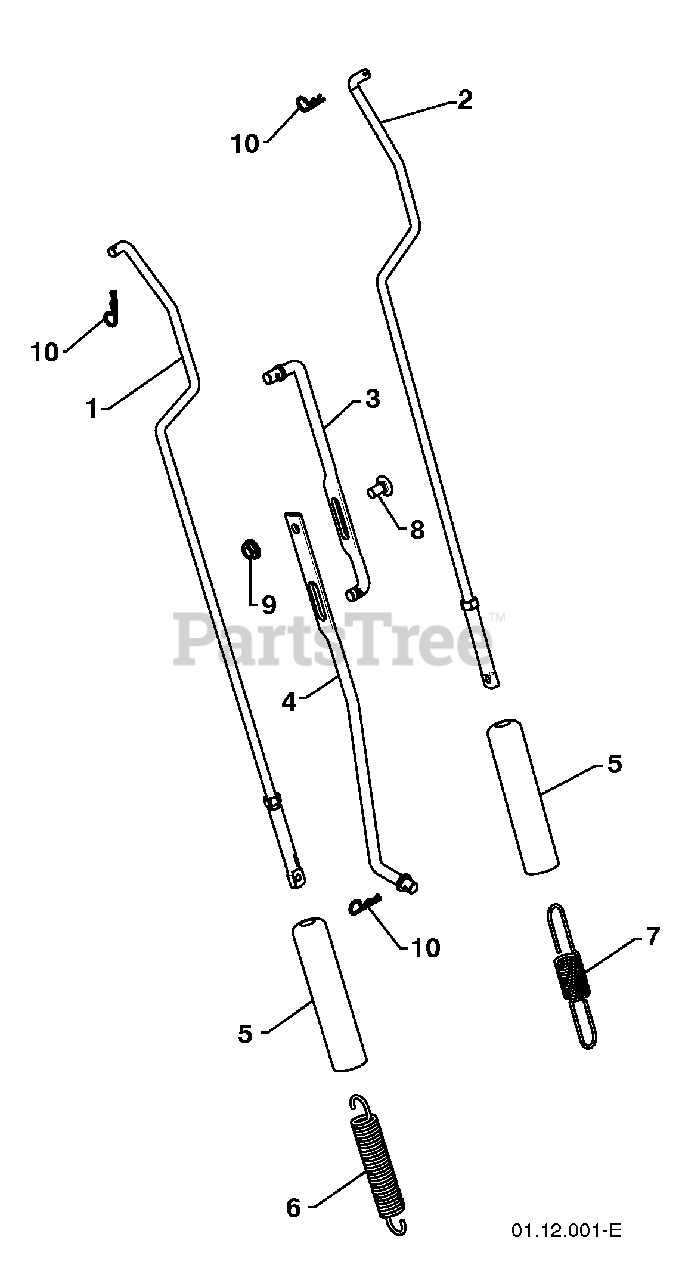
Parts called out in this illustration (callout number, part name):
1	IMPELLER ROD
2	TRACTION ROD
3	SHIFTER ROD TOP
4	SHIFTER ROD BOTTOM
5	SPRING SLEEVE
6	IMPELLER SPRING
7	TRACTION SPRING
8	CARRIAGE BOLT 5/16-18 X .75
9	NUT 5/16-18
10	RETAINER
